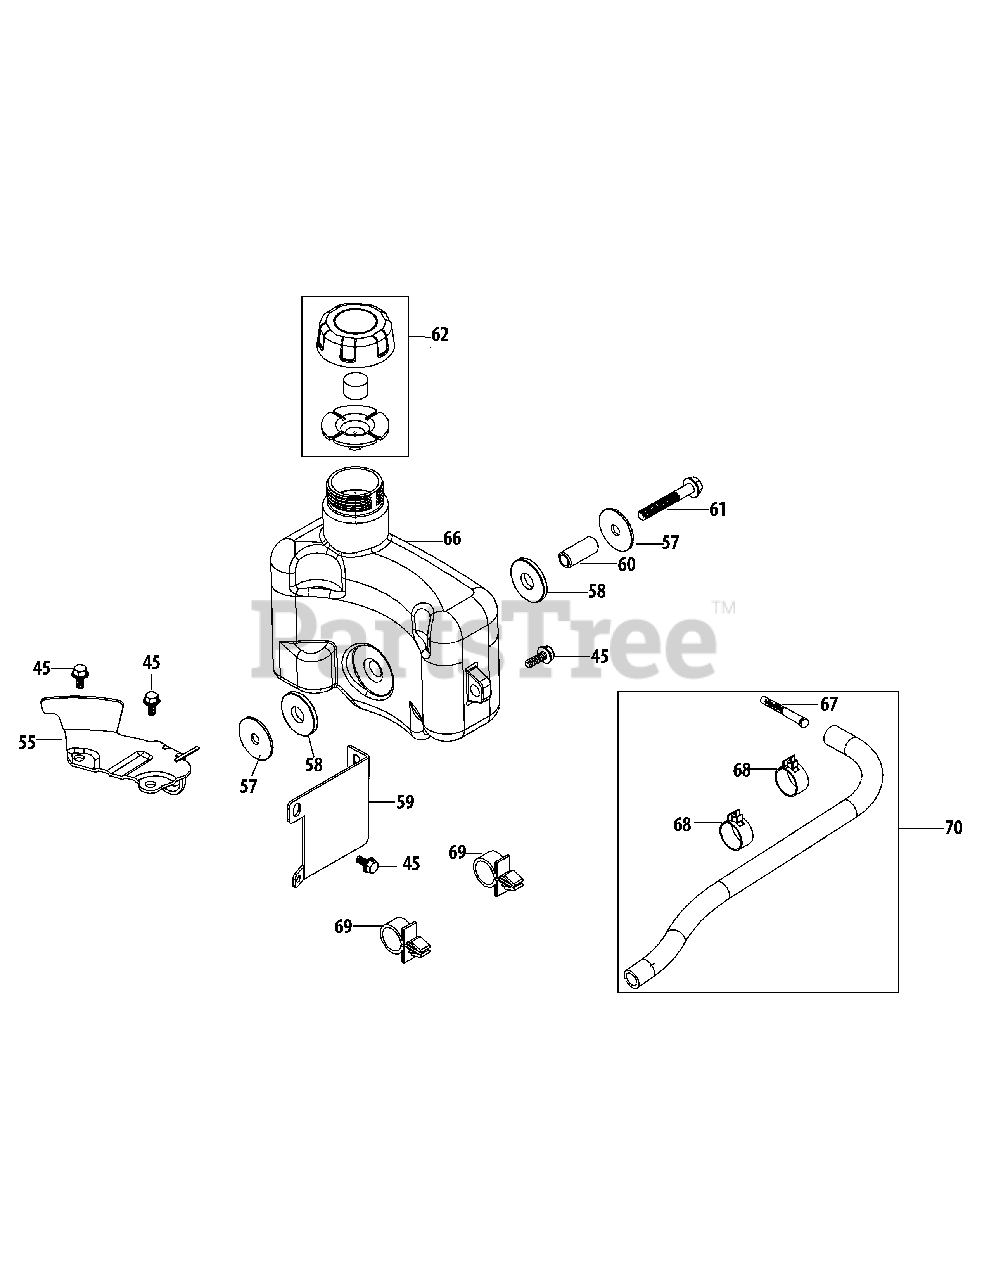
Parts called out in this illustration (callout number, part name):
45	Bolt M6×14
55	Fuel Tank Bottom Bracket
57	Fuel Tank Washer
58	Rubber Bushing
59	Fuel Tank / Label Bracket
60	Fuel Tank Bushing
61	Bolt M8X50
62	Fuel Cap Assembly
66	Fuel Tank Assembly
67	Fuel Filter
68	Fuel Hose Clamp
69	Plastic Support Clamp
70	Fuel Line Kit
